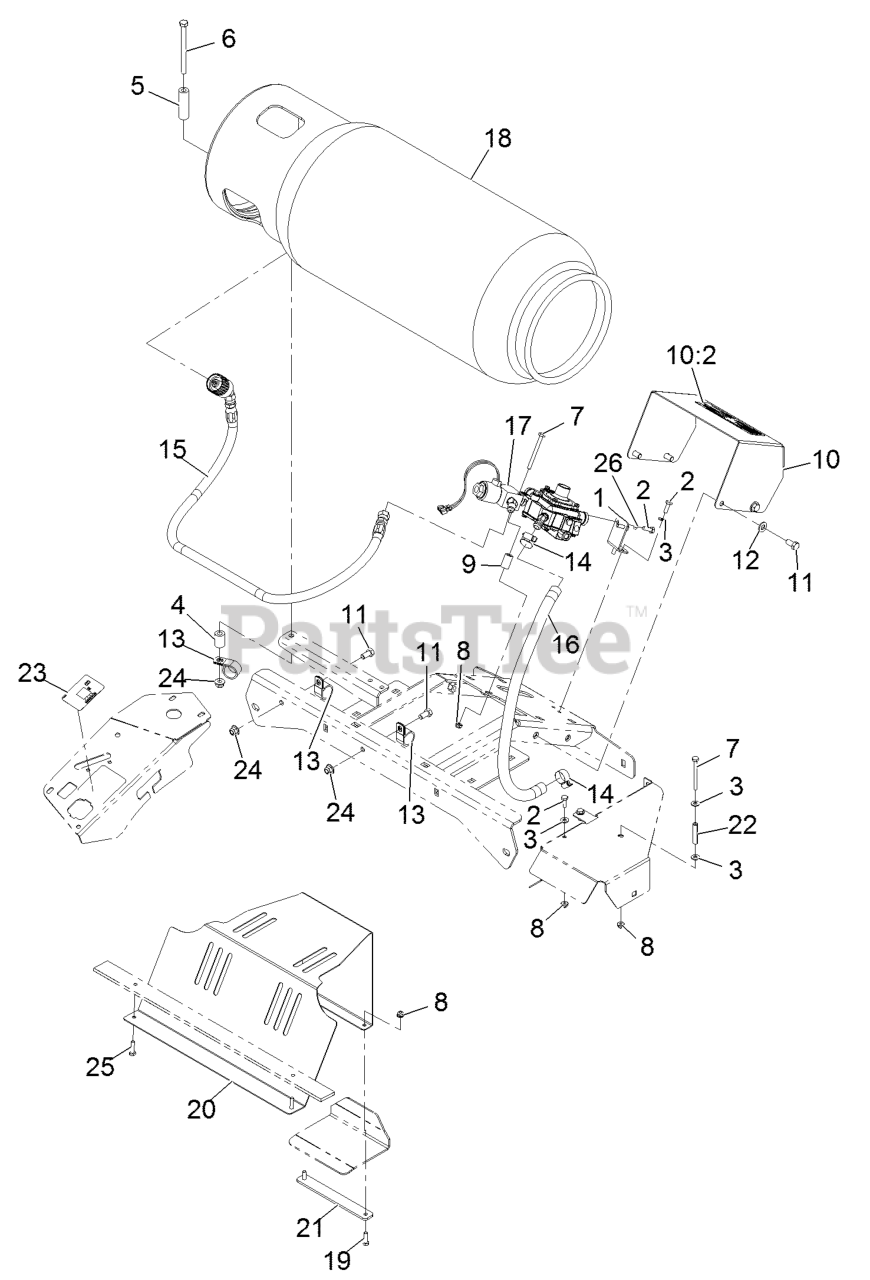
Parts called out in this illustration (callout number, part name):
1	BRACKET-REGULATOR
2	SCREW-HH
3	WASHER-FLAT
4	SPACER-HYDRO CONTROL, LH
5	SPACER-ANCHOR, CLUTCH
6	SCREW-HH
7	SCREW-HH
10	COVER ASM
10:2	DECAL-TANK REPLACEMENT
11	SCREW-HH
12	WASHER-FLAT
13	CLIP-LOOM
14	CLAMP-HOSE
15	LPG FUEL HOSE ASM
16	HOSE-LPG
17	LPG REGULATOR ASM
19	SCREW-HH
20	SHEILD-FAN
22	SPACER-SPLIT
23	DECAL-METER, HOUR
24	NUT-HF, NI
25	SCREW-HH
26	WASHER-SPRING
